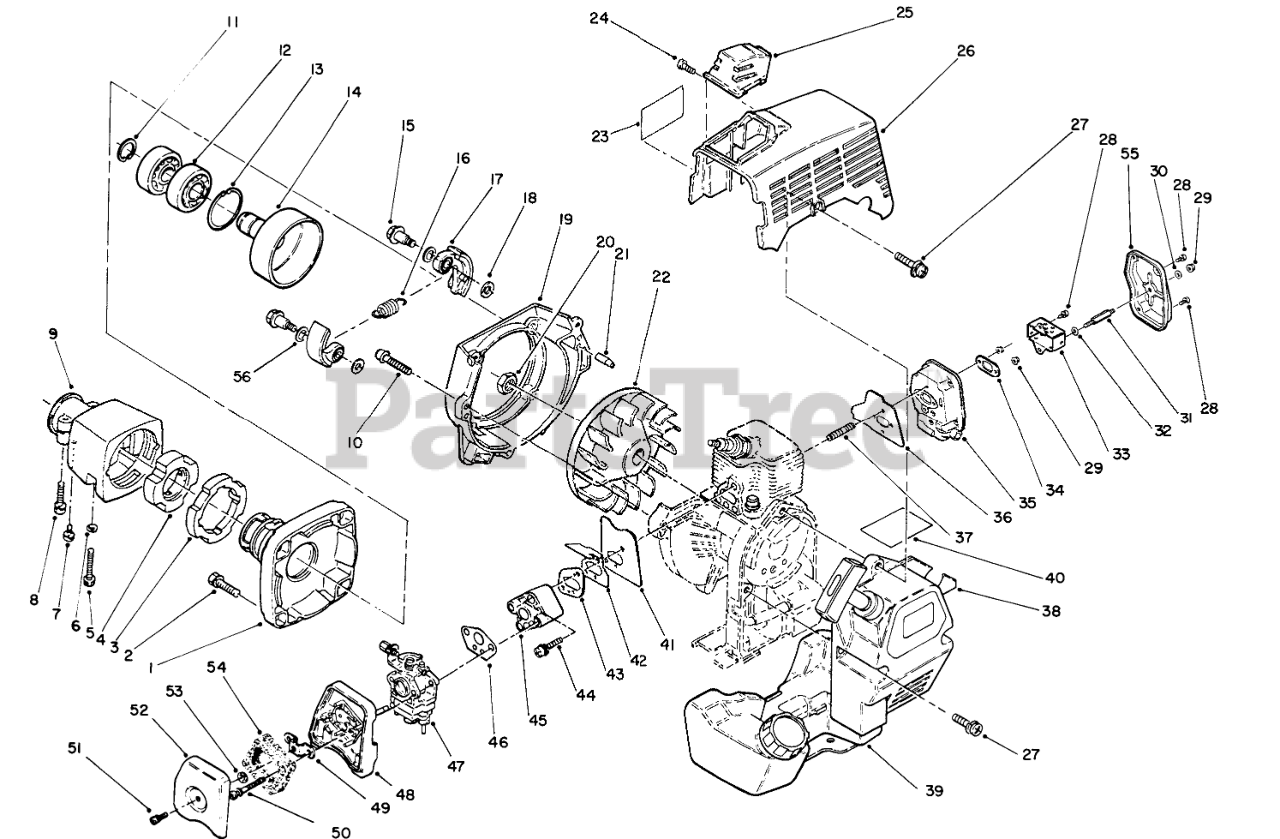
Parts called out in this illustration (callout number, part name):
1	Case-Clutch
3	RUBBER, CUSHION (A)
4	RUBBER, CUSHION (B)
6	Washer
7	Screw/Washer
8	BOLT-WASHER/ENG
9	Holder
11	SNAP RING
12	BALL BEARING
13	SNAP RING
14	DRUM, CLUTCH
15	CLUTCH BOLT
16	CLUTCH SPRING
17	CLUTCH SHOE
18	WASHER
19	FAN CASE
23	DECAL-SURFACE, HOT
24	SCREW & WASHER
25	SPARK PLUG GUARD
26	TOP COVER
27	SCREW & WASHER
28	SCREW & WASHER
29	MUFFLER FLANGE NUT
30	GASKET
31	DUAL BOLT
32	WASHER
33	Baffle
34	Plate
35	MUFFLER ASSEMBLY
36	MUFFLER GASKET
37	STUD BOLT
38	RECOIL ASSEMBLY
39	FUEL TANK ASM
40	Decal-Fuel Mix
41	INSULATOR GASKET
42	PLATE
43	INSULATOR GASKET
44	SCREW & WASHER
45	INSULATOR
46	CARBURETOR GASKET
47	CARBURETOR ASM
48	CLEANER CASE
49	BRACKET
50	SCREW W/ WASHER
51	SCREW & WASHERE
52	CLEANER COVER
54	CLEANER ELEMENT
55	Cover-Muffler
56	Washer-Wave
